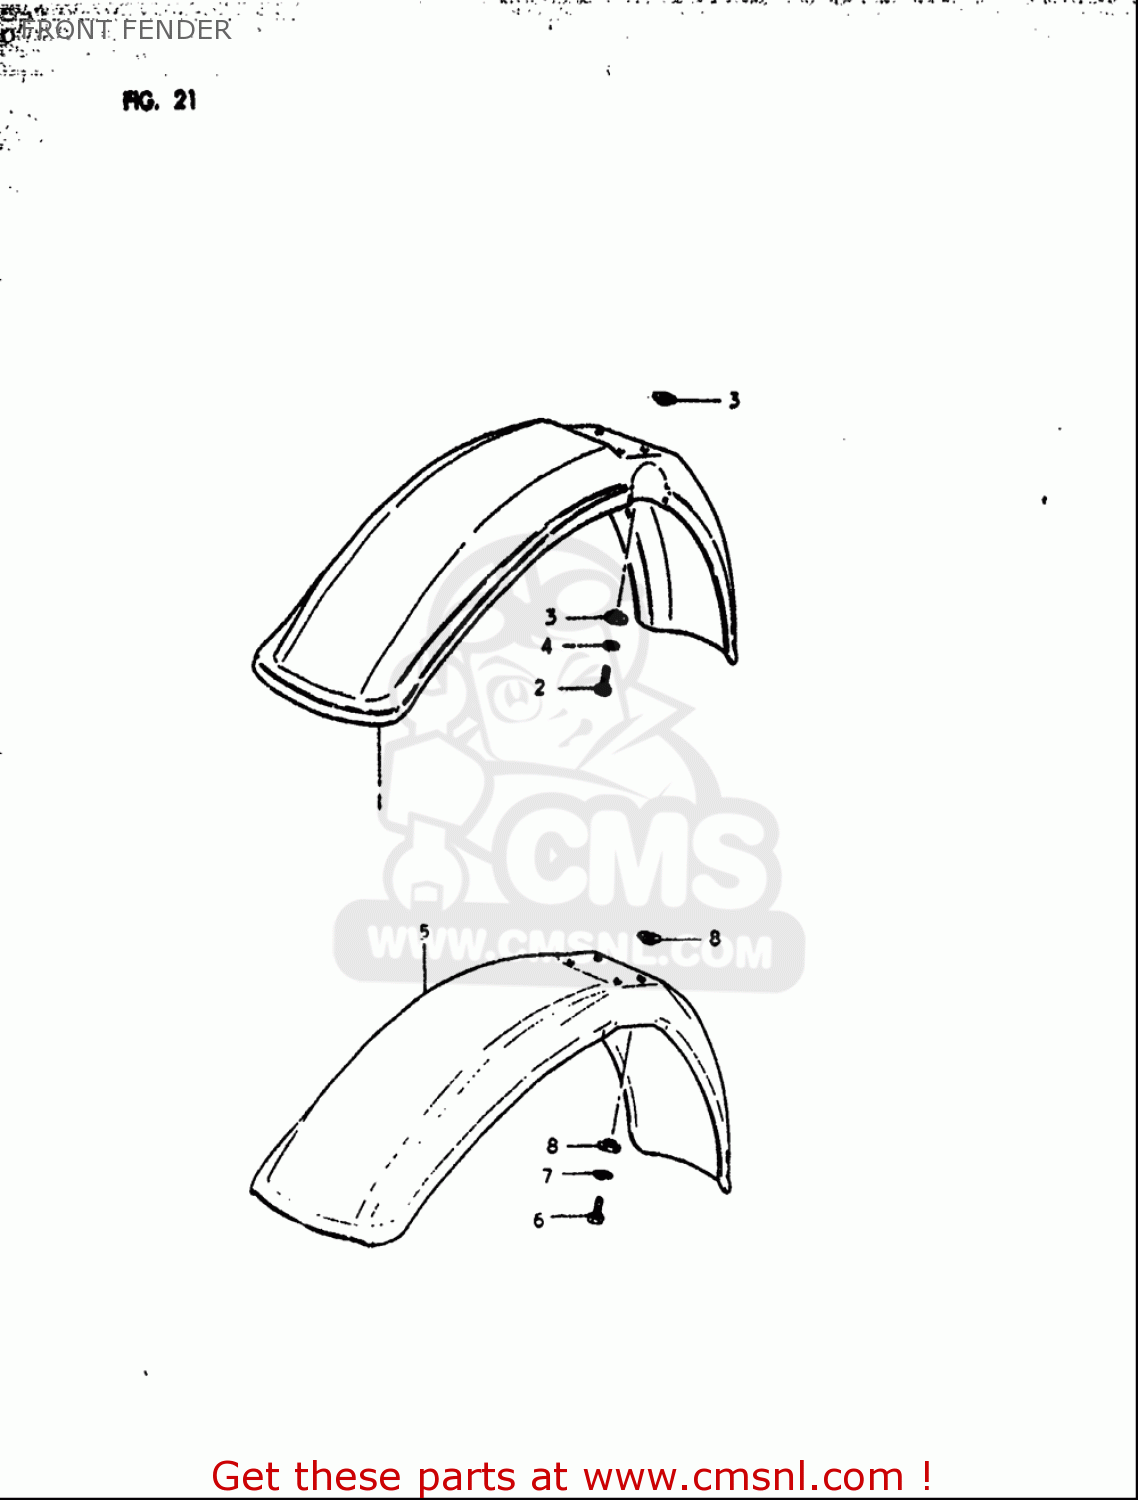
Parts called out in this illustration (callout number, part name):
2	BOLT
3	WASHER
4	WASHER,LOCK
5	FENDER,FR
6	BOLT
7	WASHER,LOCK
8	WASHER
